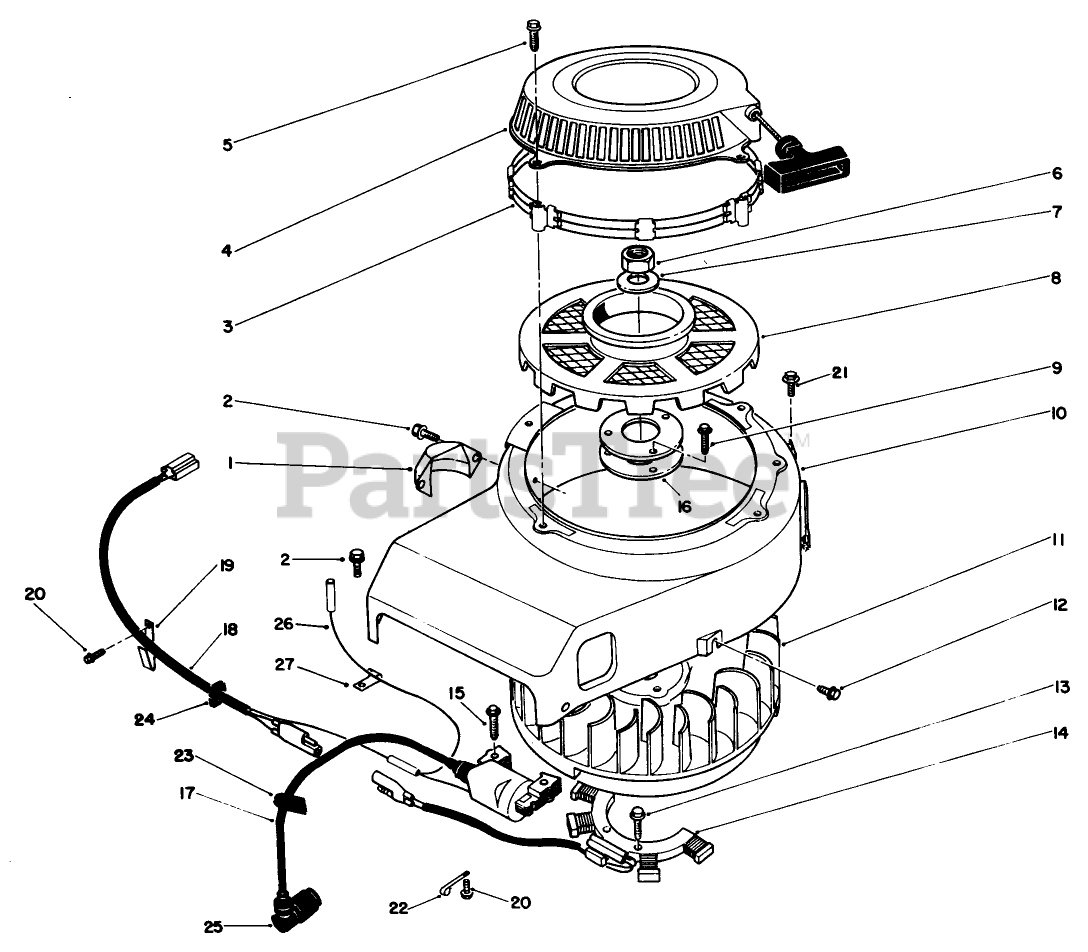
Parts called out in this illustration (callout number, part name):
4	Recoil Starter Assembly
5	BOLT-FLANGED (6X10)
9	Bolt-Flanged (8X12)
10	Housing-Fan
11	Flywheel
12	BOLT-FLANGED (6X10)
18	Harness
20	Bolt-Flanged (6X10)
21	Bolt-Flanged (6X14)
23	Grommet
24	Grommet
25	Cap-Spark
26	Lead Wire
